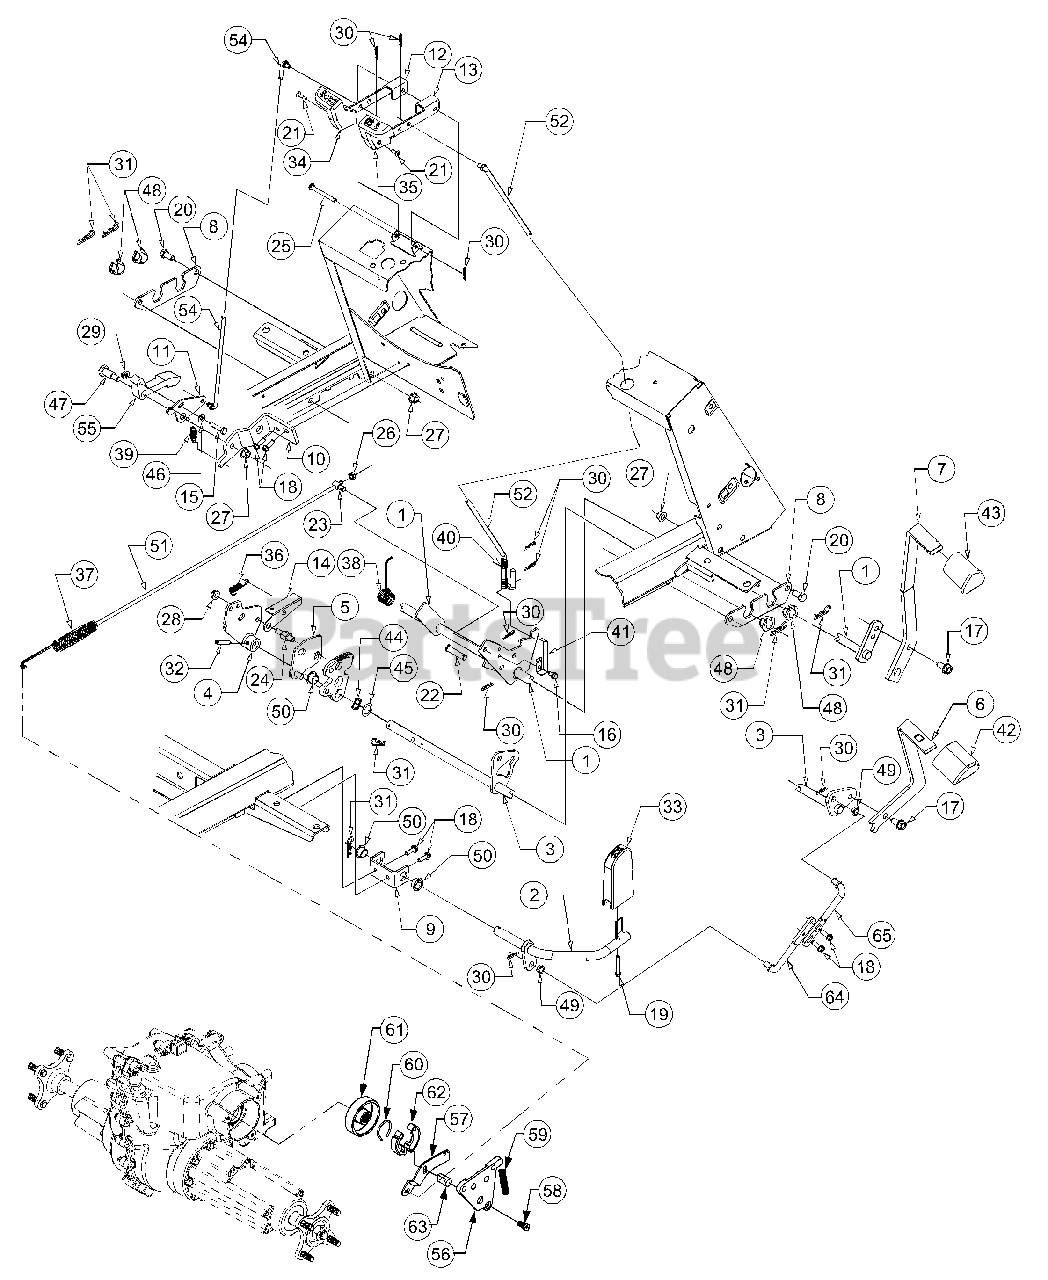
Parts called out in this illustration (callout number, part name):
1	Shaft Assy, Brake
4	Cam Assy, Control
5	Plate Assy, Disengagement
8	Plate, Bearing Mounting
10	Bracket, Cruise
11	Plate, Rod Adjustment
15	Screw, Hex Cap, 1/4-20 x 1.25
16	Screw, Hex Wash Hd Tapp 1/4-20 x .5
17	Screw, Hex Wash Hd Tapp 3/8-16x .75
18	Screw, Hex Wash Hd Tapp 1/4-20x .75
19	Screw, Truss Mach, #12 x 1.5
20	Screw, Hex Cap, 3/8-16 x .75 GR5
21	Screw, Phil Hd Pan, #10-24 x .75
22	Pin, Clevis, 3/8 x 1.62
23	Ferrule, Adjustment, 1/4-20 Thrd
24	Stud, Actuator
25	Pin, Clevis, .25 x 2.38
26	Nut, Hex Sems, 1/4-20
27	Nut, Hex Flange Lock, 3/8-16
28	Nut, Hex Flange Lock, 5/16-18
29	Nut, Hex Flange Lock, 1/4-20
30	Pin, Internal Cotter, 5/16 Dia x 1.12
31	Pin, Internal Cotter, 3/8 Dia x 1.62
32	Pin, Spiral Spring, 1/4 x 1.5
33	Pedal, Reverse
34	Knob, Cruise
35	Knob, Brake Lock
36	Spring, Extension, .38 OD x 2.1
37	Spring, Extension
38	Spring, Torsion
39	Spring, Extension, .437 OD x 1.32
40	Spring, Compression, .50 x 2.23
41	Spring, Switch Actuator
42	Pad, Forward Foot Control
43	Pad, Brake Foot
44	Washer, Wave, .625 x .885 x .015
45	Washer, Flat, .635 x 1.0 x .020
46	Washer, Flat, 1/4 x .63 x .051
47	Shoulder Bolt, .50 OD x .840
48	Bearing, Hex Flange Split
49	Bearing, Flange, .375 x .58 x .25
50	Bearing, Flange, .626 x .93 x .344
51	Rod, Brake
52	Rod, Parking Brake
54	Rod, Cruise
55	Latch, Cruise
56	Plate, Brake
57	Arm, Brake
58	Screw, Low Hd Cap, 3/8-16 x .75
59	Spring, Compression
60	Spring, Brake
61	Drum, Brake
62	Shoe, Brake
63	Actuator, Brake Shoe
64	Rod, Rear Connecting
65	Rod, Front Connecting
